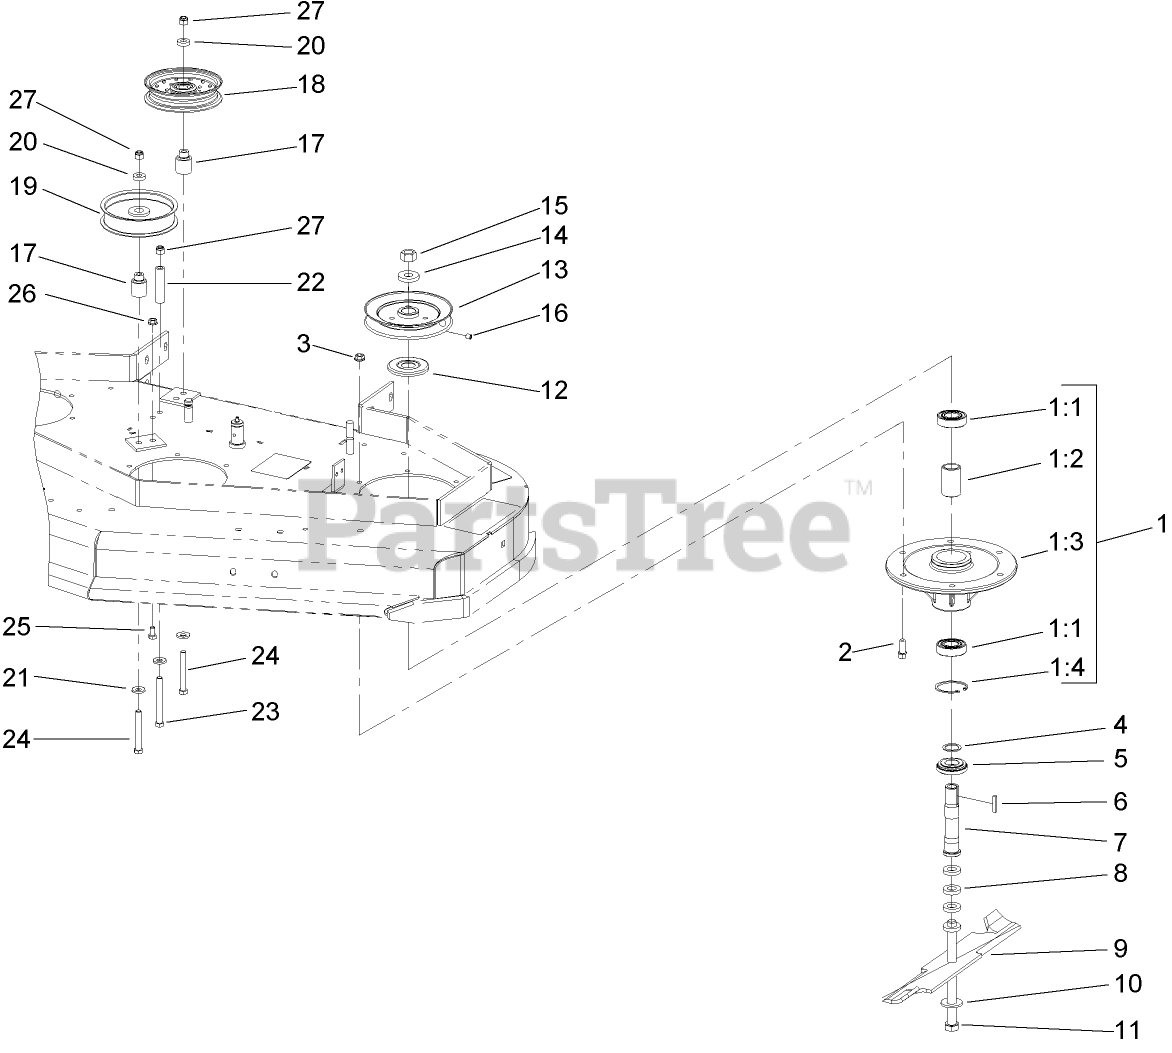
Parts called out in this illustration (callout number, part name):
1	SPINDLE HOUSING ASM
1:1	BEARING
1:2	SPACER-BEARING
1:3	HOUSING-SPINDLE
1:4	RING-SNAP
2	SCREW-HWH
3	NUT-HHF, WHIZ
4	WASHER-SPACER
5	SPACER-GUARD, BOTTOM
7	TUBE-SPINDLE, SHORT
8	SPACER
9	BLADE-16.5 INCH (HIGH FLOW)
10	WASHER-SPRING
11	SCREW-CAP, HH
12	Guard-Bearing, Top
13	SHEAVE
14	WASHER-RETAINER, SHEAVE
15	NUT-HEX
16	SCREW-SET
17	BUSHING-IDLER
18	IDLER-PULLEY, FLAT
19	PULLEY-IDLER
20	SPACER
21	WASHER-BELLEVILLE
22	SPACER
23	SCREW-HH
24	SCREW-HH
25	SCREW-HH
26	NUT-HF
27	NUT-LOCK, NI
